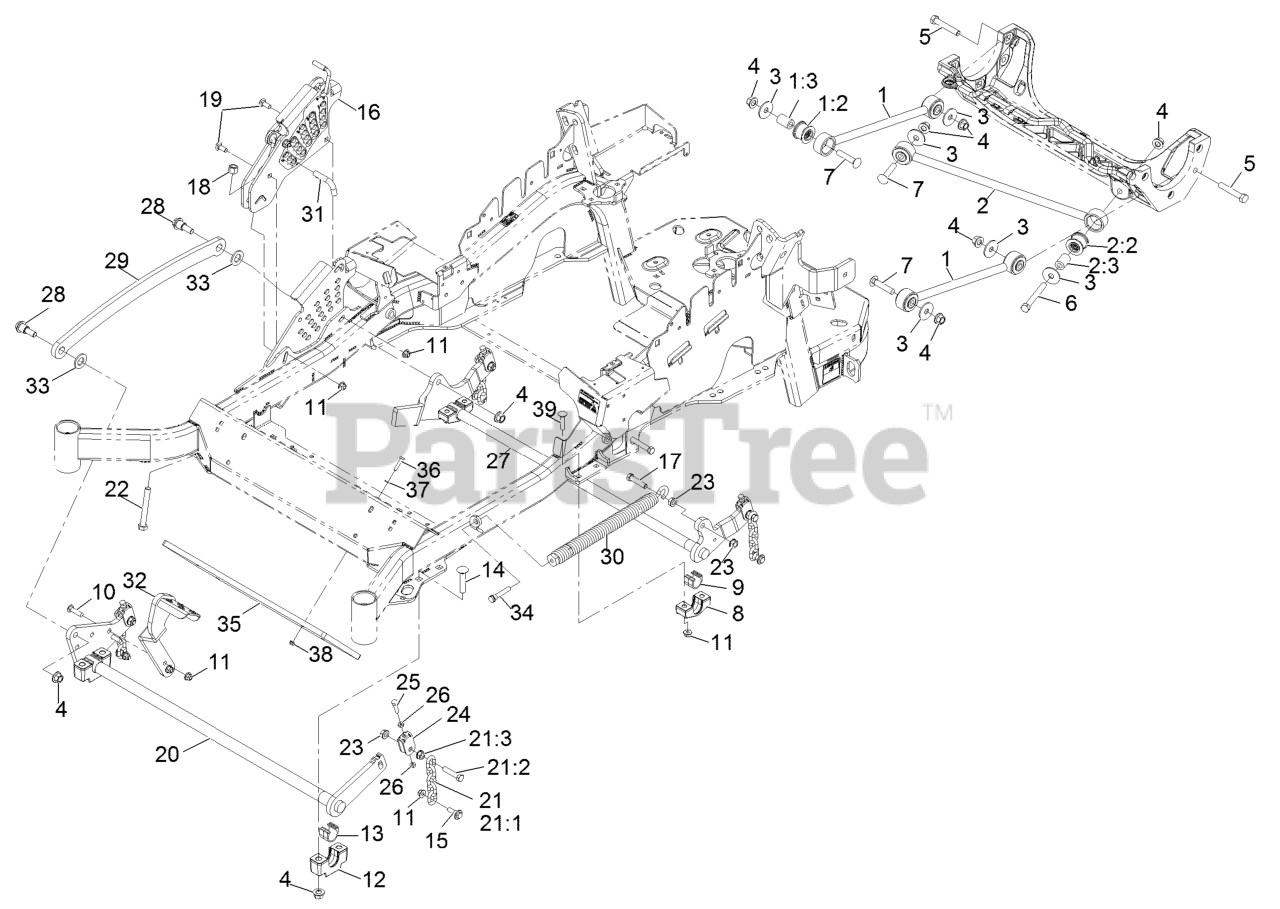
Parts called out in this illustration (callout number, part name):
1	DECK STRUT ASM
1:2	BUSHING-SUSPENSION, RUBBER
2	PANHARD ROD ASM
2:2	BUSHING-SUSPENSION, RUBBER
3	WASHER-THRUST
4	Nut-Lock 1/2-13
5	SCREW-HH
6	SCREW-HH
7	SCREW-CARR
9	BEARING-CROSS SHAFT, REAR
10	SCREW-CARR
11	NUT-HF, NI
12	SUPPORT-CROSS SHAFT, BEARING
13	BEARING-CROSS SHAFT, FRON
14	Bolt-Carriage 1/2-13 X 2 1/2 Spl Neck
15	SCREW-SHOULDER, HHF
16	HOC ASM
17	SCREW-HH
18	NUT-LOCK, NI
19	BOLT-CARR
21	DECK LIFT CHAIN ASM
21:1	CHAIN-LIFT, DECK
21:2	SCREW-HH
22	BOLT-TAP
24	YOKE-ADJUST, DECK
25	SCREW-HH
26	NUT-JAM
27	LIFT-DECK, REAR
28	SCREW-SHOULDER, HHF 1/2-13 X 1.12
29	LINK-LIFT, DECK
30	SPRING-EXTENSION
31	PIN-HOC
32	LEVER-FOOT
33	WASHER-FLAT
34	BOLT-SHOULDER
35	WEIGHT,TOE BOARD
36	SCREW-HH
37	WASHER-FLAT
39	SCREW-CARR
